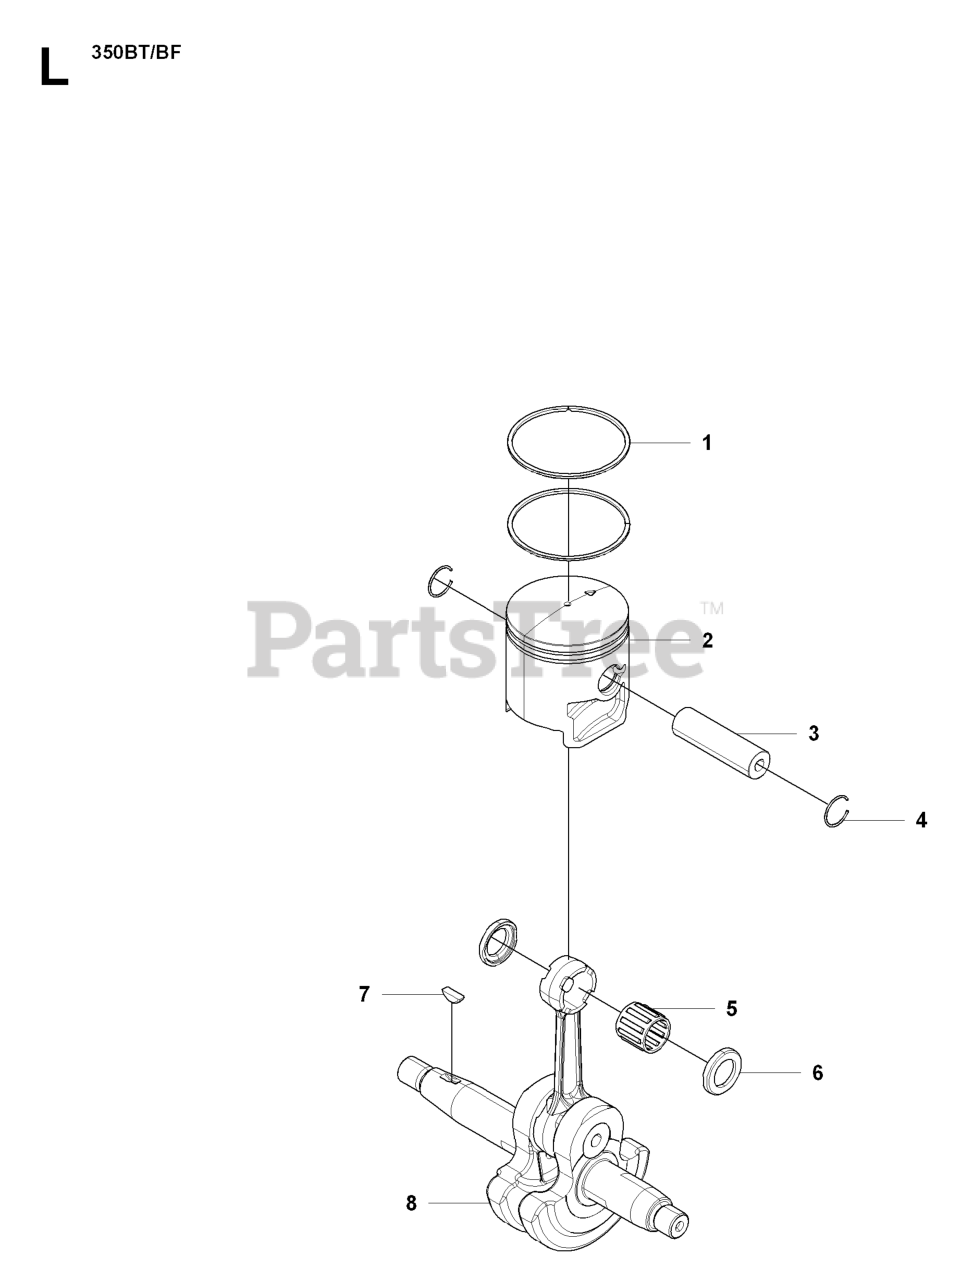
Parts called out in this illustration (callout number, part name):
1	PISTON RING
3	PISTON PIN
5	BEARING
8	CRANKSHAFT
